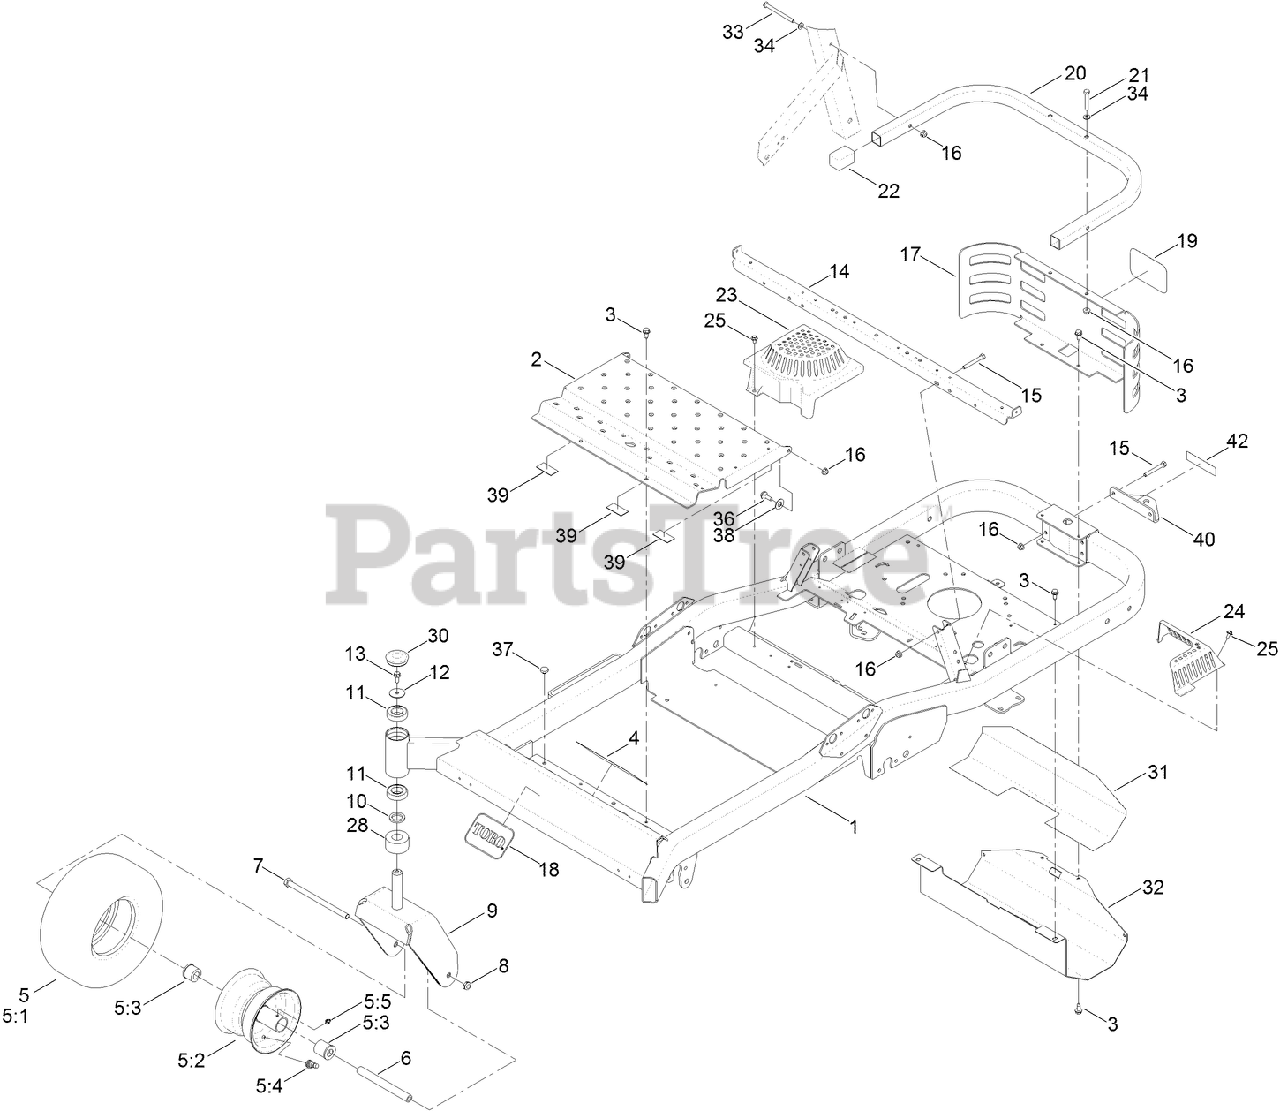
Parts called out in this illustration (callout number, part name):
1	FRAME ASM
2	PAN-FLOOR
3	SCREW-HWHTF
4	DECAL-DANGER
5	TIRE AND WHEEL ASM
5:1	TIRE-13 INCH SMOOTH
5:2	RIM-6 INCH
5:3	BUSHING-FLANGE
5:5	FITTING-GREASE
6	SPANNER
7	SCREW-HH
8	NUT-HEX
9	FORK-CASTER
10	WASHER-THRUST
11	BEARING-BALL
12	WASHER-FLAT
13	SCREW-HHF
14	SUPPORT-SEAT
15	SCREW-HH
16	NUT-HF, NI
17	GUARD-REAR
18	DECAL
20	TUBE-GUARD
21	SCREW-HH
23	COVER-FAN, RH
24	COVER-FAN, LH
25	SCREW-HHFTF
28	SPACER-CASTER
30	CAP-GREASE
31	FOIL-HEAT SHIELD
32	SHIELD-HEAT
33	SCREW-HH
34	WASHER-PLAIN
36	SCREW-SHOULDER
37	BUMPER
38	WASHER-TEFLON
39	PAD-RUBBER
40	BRACKET-HITCH
